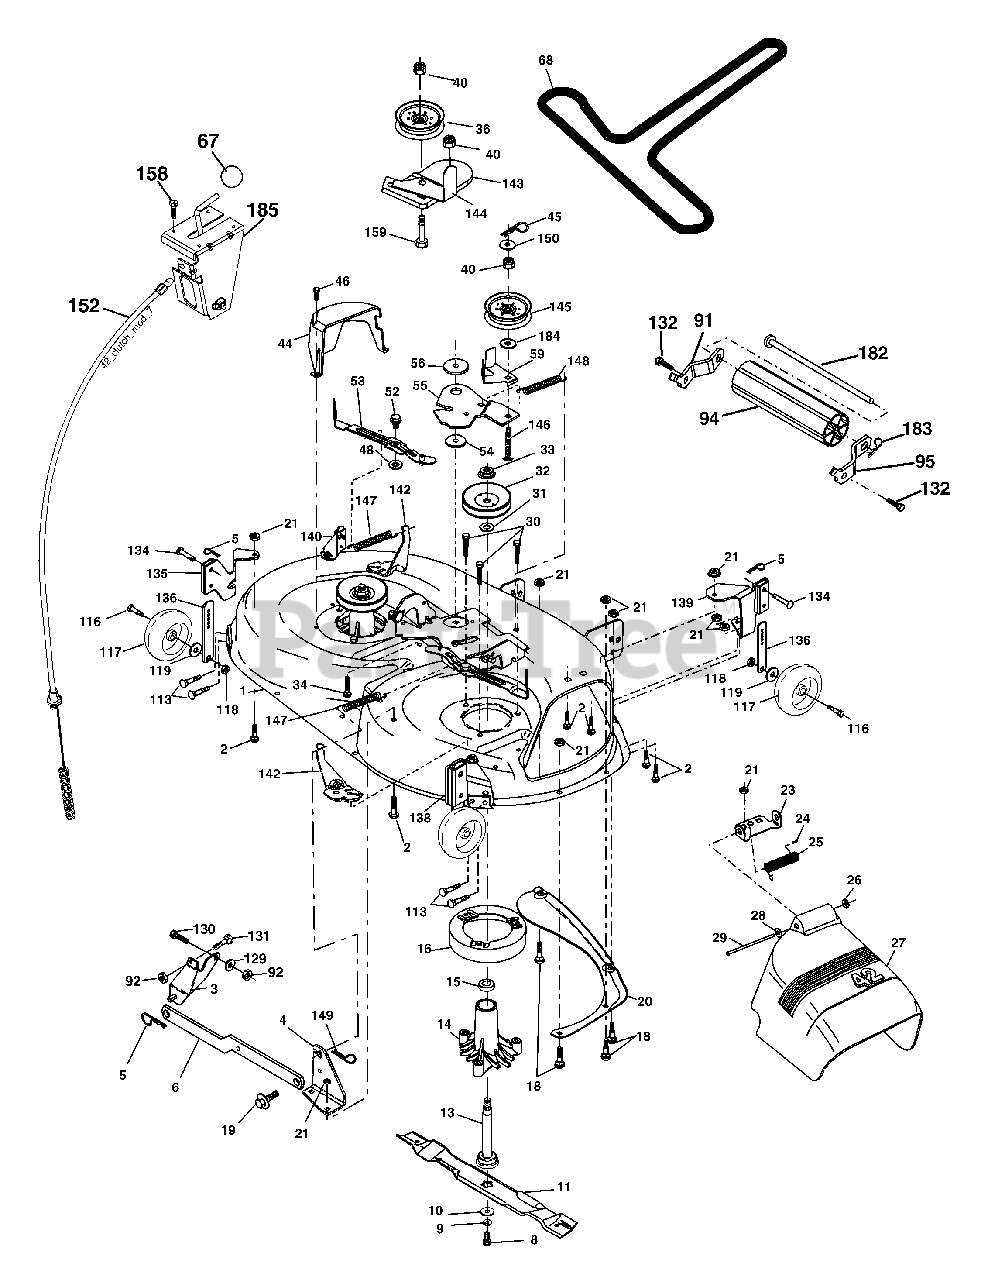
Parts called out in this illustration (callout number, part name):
1	Deck Asm 42"weldment
2	Bolt Rdhd Sqnk 5/16-18 unc x 3/4
3	Bracket Asm Fr Sway Bar 38/42
4	Bracket Asm Deck 42"sway Bar
5	Retainer Spring
6	Deck Sway Bar
8	Bolt 3/8 - 24 x 1.25 Gr. 8
9	Washer Lock Hvy 3/8
10	Washer Hard Blade Mower Vented
11	Blade, 42"
11	Blade, 42" Mulching Premium
11	Blade, 42" Hi-Lift
13	Shaft Asm W/lower Bearing
14	Housing Mandrel Vented
15	Bearing Ball Mandrel
16	Stripper Mower
18	Bolt Rdhd Sqnk 5/16-18 x 5/8
19	Bolt Shoulder
20	Baffle Vortex 42
21	Nut Crownlock 5/16-18 unc
23	Bracket Deflector Mower 42"
24	Cap Sleeve 80x 112 Blk Mower
25	Spring Torsion Deflector 2 52
26	Nut Push Phos & Oil
27	Shield Deflector Mower 42" Blk
28	Washer 11/32 x 5/8 x 16 Ga.
29	Rod Hinge 42"6 75 Wlg
30	Screw Thd Rolling
31	Washer Spacer
32	Pulley Mandrel 42"
33	Nut Toplock Flng
34	Bolt Carr Sh. 3/8-16 x 1-1/2 Gr. 5
36	Pulley Idler Flat
40	Nut Lock Flg 3/8-16 unc
44	Guard Mandrel LH Black
45	Spring Retainer 1" Zinc/cad
46	Screw Hex Thd Cut 1/4-20 x 5/8 T
48	Washer Hardened Smaller
52	Bolt Shoulder 5/16-18 unc Blkz
53	Arm Asm Pad Brake
54	Washer Hardened
55	Arm Idler 42"mower LT/YT
56	Spacer Retainer Mower
59	Guard TUV Idler
67	Knob Rd 3/8-16 Plstc Thds Blk
68	V-Belt Mower 42"
91	Bracket Asm Noseroller LH
92	Nut 3/8-16 unc
94	Roller Nose 38 & 42
95	Bracket Asm Noseroller RH
113	Screw 5/16-18 x 3/4
116	Bolt Shoulder 3/8-16 x 3-5/8
117	Wheel Gauge Donut Wide
118	Nut Centerlock 3/8-16
119	Washer 3/8 x 7/8
129	Washer 13/32 x 13/16 x 12 Ga.
130	Bolt 3/8-16 x 1 Gr.5
131	Bolt 3/8-16 x 1
132	Screw 3/8-16 x .75
134	Pin Head Rivet
135	Bracket Asm Whl Ga. Rear LH
136	Bar Adjusting Gauge Wheel
138	Bracket Asm Whl Ga. Rear RH
139	Bracket Asm Whl Ga. Front Rh
140	Bracket Asm Whl Ga. Front LH
142	Arm Spring Brake Mower
143	Bracket Arm Idler 42"
144	Keeper Belt 42" Clutch
145	Pulley Idler Flat
146	Bolt Carriage Idler
147	Spring Extension
148	Spring Return Idler
149	Retainer Spring Yellow
150	Washer 9/32 x 3/4 x 10 Ga.
152	Clutch Cable 42"
158	Screw Hex Thd Cut 1/4-20 x 1/2
159	Bolt Rdhd Sqn 3/8-16 unc x 1-3/4
182	Rod Roller Nose Std.
183	Retainer Spring
184	Washer 13/32 x 7/8 x 10 Ga.
185	Head Asm Cable Clutch
